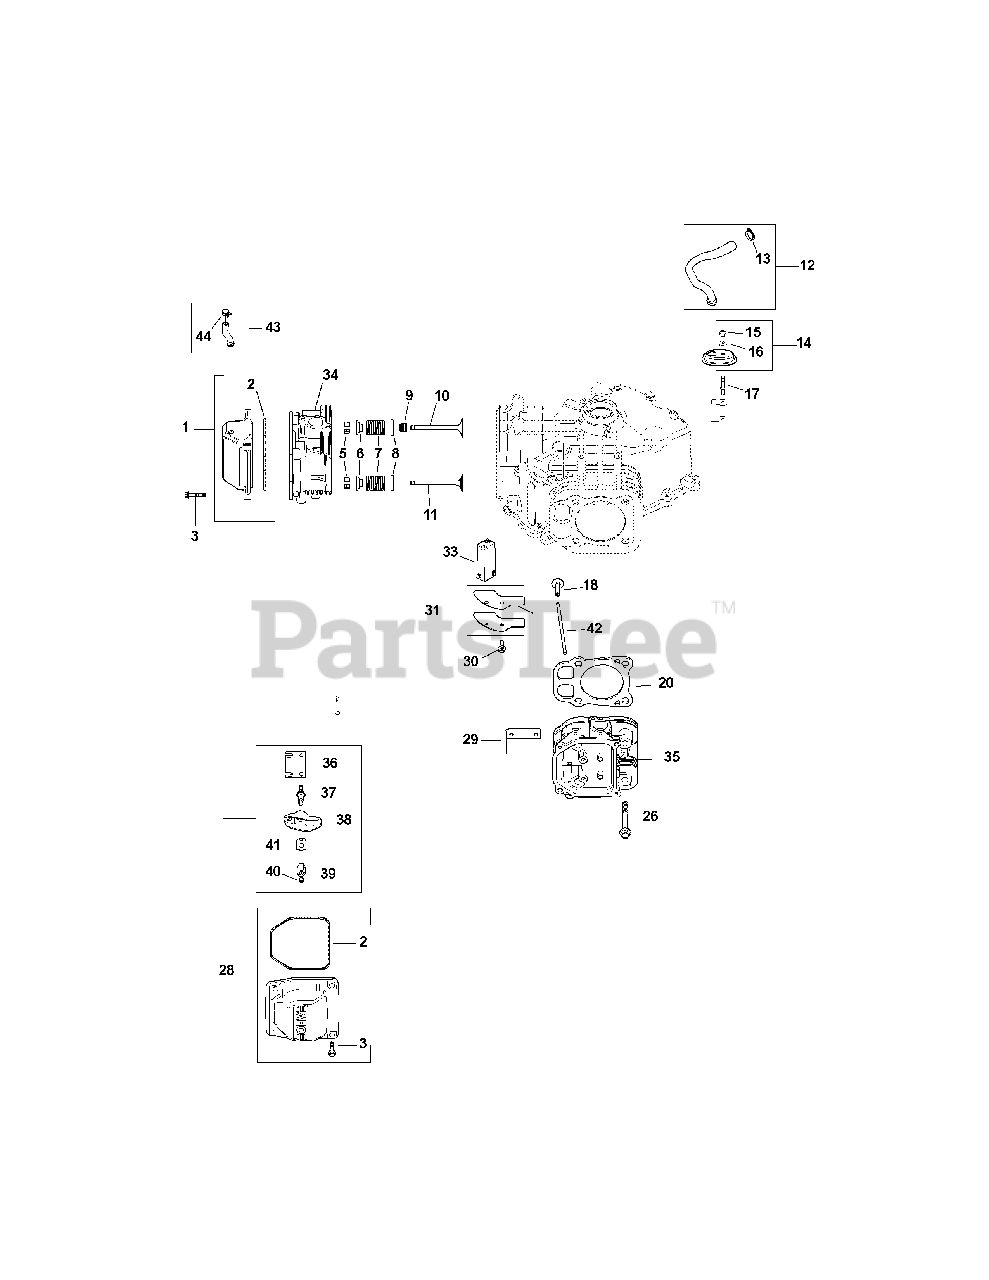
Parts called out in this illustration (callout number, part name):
1	Breather Valve Cover Kit (Inc. 2)
2	Valve Cover O-Ring
3	Flg. Screw, M6 X 1.0 X 30
5	Retainer Kit
6	Valve Spring Cap
7	Valve Spring
8	Spring Retainer
9	Valve Stem Seal
10	Intake Valve (Std)
11	Exhaust Valve (Std)
12	Kit, Breather Hose Kit (Inc. 13)
13	Hose Clamp, 1/2
14	Breather Housing Kit (Inc. 15, 16)
15	Lock Nut, M 5 X .8
16	Sealing Washer
17	Breather Cover Stud
20	Cylinder Head Gasket Kit
26	Flg. Screw, M 10 X 1.5 X 90
28	Breather Valve Cover Kit (Inc. 2 & 3)
29	Lifting Strap
30	Flg. Thd. Frm. Screw, M6 X 1.0 X 16
31	Breather Cover Kit (Inc. 32)
33	Breather Filter
34	#1 Cylinder Head Assembly Kit
35	#2 Cylinder Head Assembly Kit
39	Hex Nut Assembly (Includes 39)
41	Rocker Arm Pivot
43	Fuel Pump Hose w/ Clamp Kit (Inc.44)
